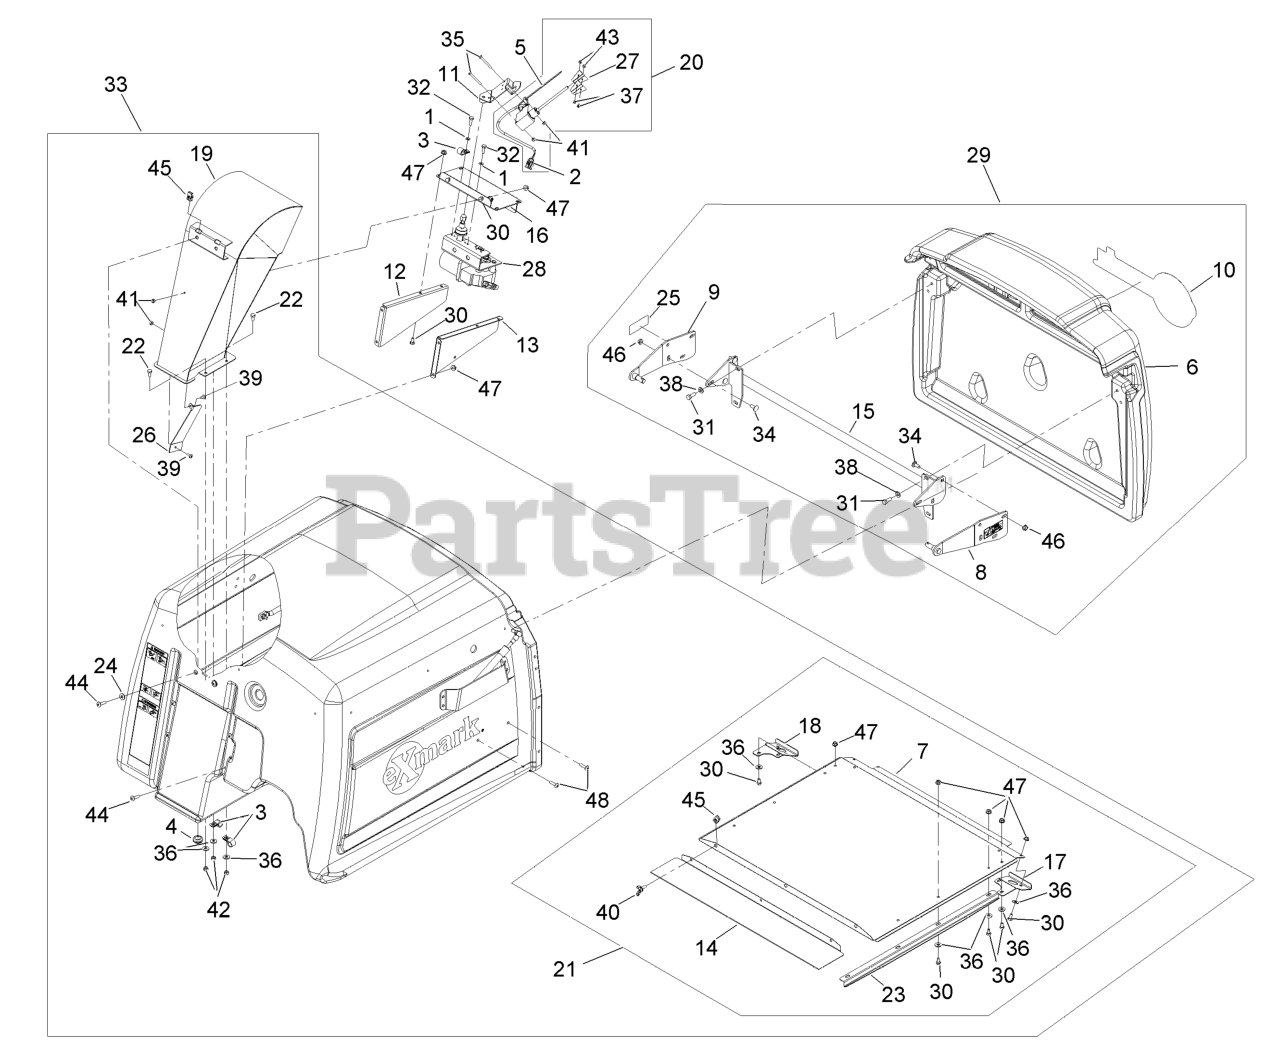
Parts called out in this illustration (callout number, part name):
1	WASHER-SPRING
2	FILL SENSOR WIRE KIT
3	CLIP-LOOM
4	GROMMET
5	TIE-PLASTIC
6	DOOR,HOPPER
7	PANEL-SCREEN, HOPPER
8	LH DOOR PIVOT ASM
9	RH DOOR PIVOT ASM
10	DECAL,EXMARK LOGO
11	MOUNT-SWITCH
12	BRACKET-DRIVE MOTOR, LH
13	BRACKET-DRIVE MOTOR, RH
14	PANEL-SCREEN, REMOVABLE
15	SUPPORT-DOOR
16	PLATE-SWITCH
17	HANDLE-SCREEN, LH
18	HANDLE-SCREEN, RH
20	ASM,FILL SENSOR
21	HOPPER SCREEN ASM
22	SCREW-HH
23	GUIDE-SCREEN
25	DECAL-PINCH POINT
26	DEFLECTOR-DISCHARGE CHUTE
27	FLAG- SENSOR, FILL
28	KIT,FILL SENSOR MOTOR
29	ASM,DOOR HOPPER
30	SCREW-HH
31	SCREW-HH
32	SCREW-HH
33	ASM,HOPPER
34	SCREW-CARR
35	SCREW-PPH
36	WASHER-FLAT
37	SCREW-PAN
38	WASHER-PLAIN
39	SCREW-PTH
40	SCREW-WING
41	NUT-LOCK, NI
42	NUT-LOCK, NI
43	NUT-HEX
44	SCREW-TTH
45	Nut-Retainer-Panel 1/4-20
